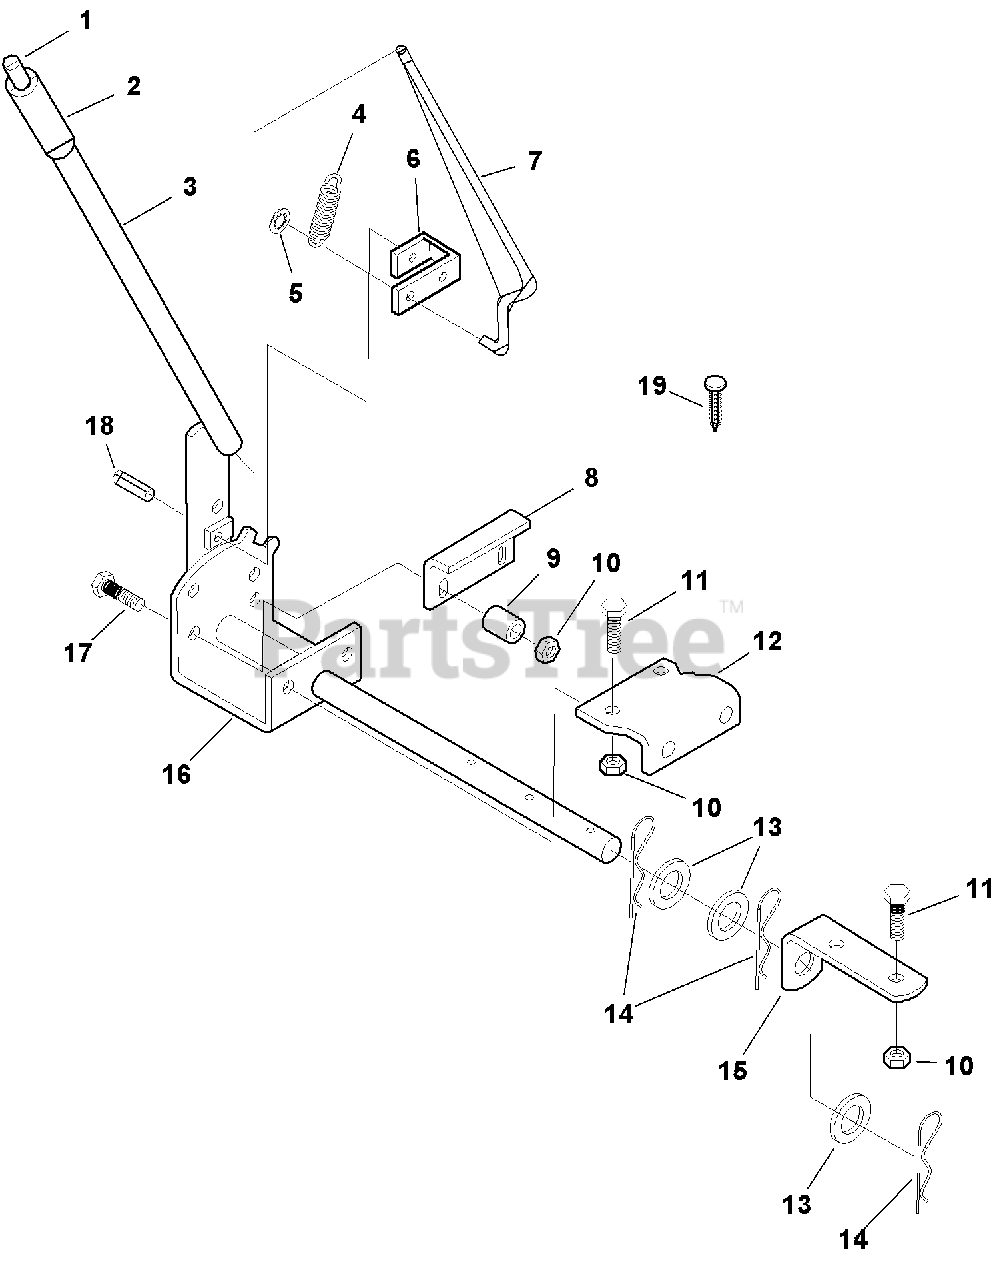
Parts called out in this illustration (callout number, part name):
3	LEVER ASSEMBLY
5	PUSH NUT, 5/16
6	LATCH, Lift Lever
8	BRACKET
10	LOCKNUT
11	CAPSCREW, Hex Head, 5/16-18 x 7/8
13	WASHER, 3/4
16	QUADRANT, Lift Lever
17	CAPSCREW, Hex Head, 5/16-18 x 1-1/4
18	ROLL PIN, 3/8 x 1
19	FASTENER, Panel
